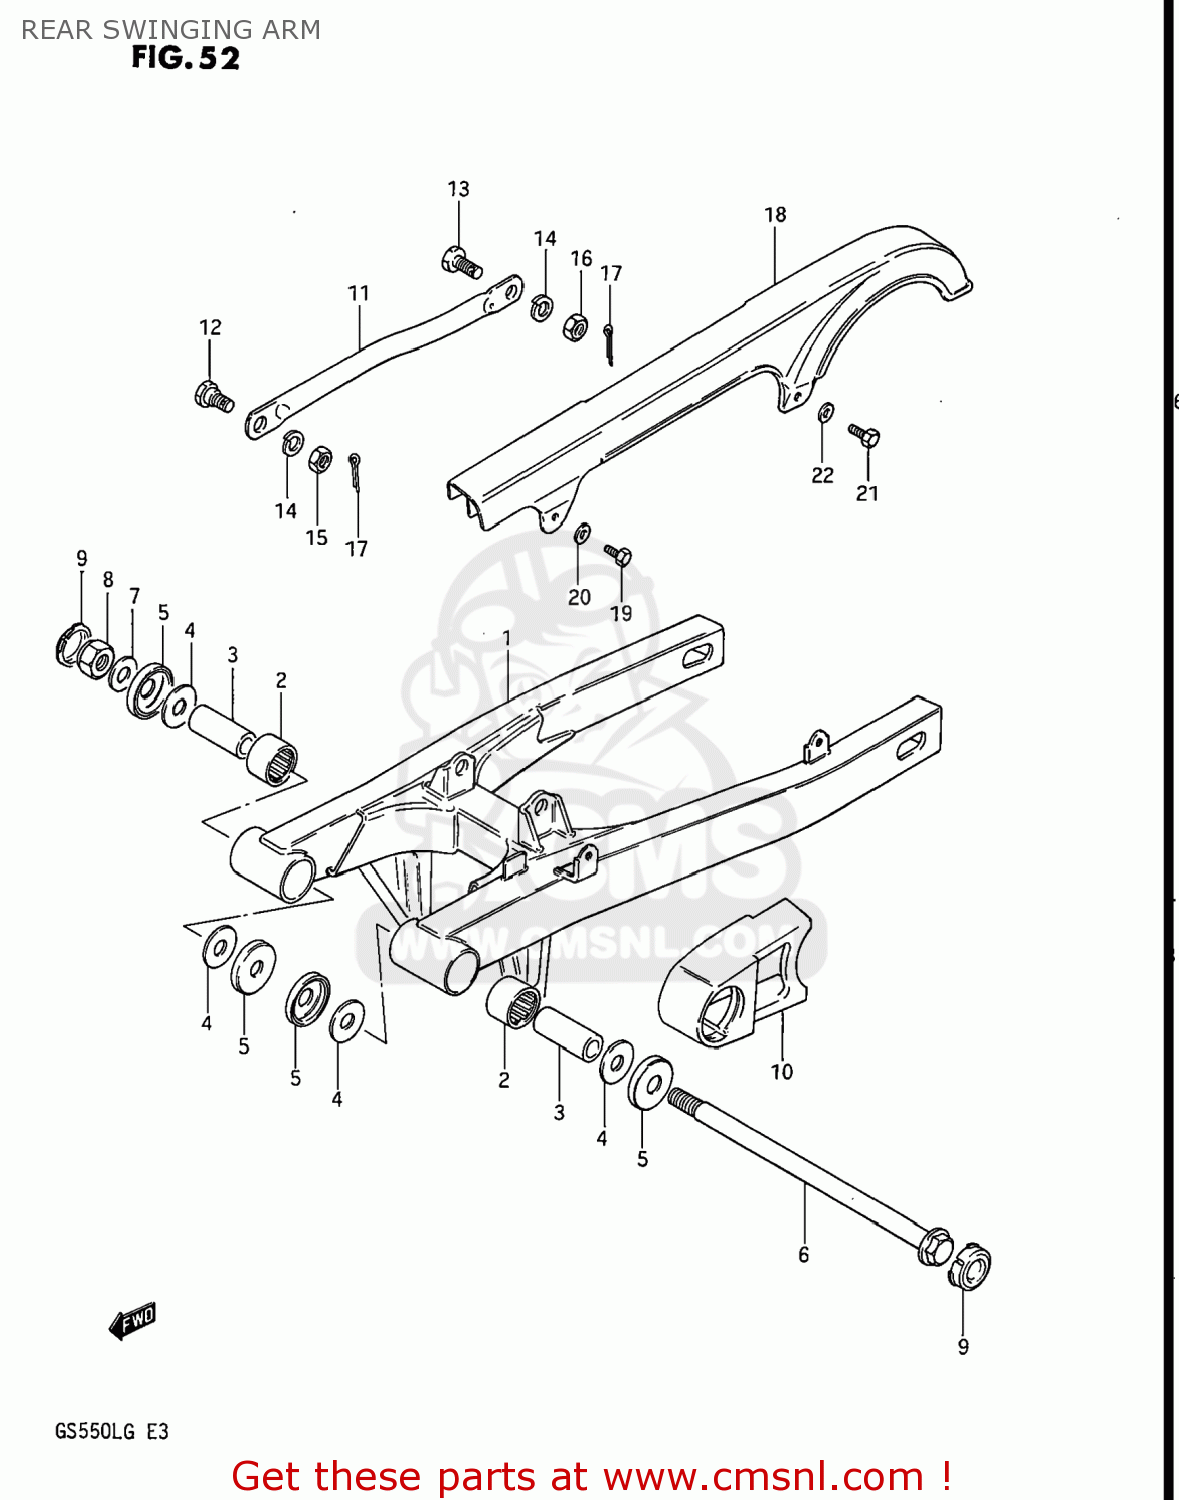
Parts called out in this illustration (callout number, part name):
1	ARM,REAR SWING
2	BEARING(25X33X30)
3	SPACER,REAR SWING ARM PIVOT
4	WASHER
5	COVER,RR SWGARM DUST SEAL
6	SHAFT,REAR SWING ARM PIVOT
7	WASHER
8	NUT
9	CAP,SWINGINGARM PIVOT
10	BUFFER,DEFENSE
11	TORQUE LINK,REAR
12	BOLT(10X24.5)
13	BOLT(10X31)
14	LOCK WASHER
15	NUT
16	NUT
17	PIN 20X20
18	CASE,CHAIN
19	BOLT
20	WASHER
21	BOLT
22	WASHER
